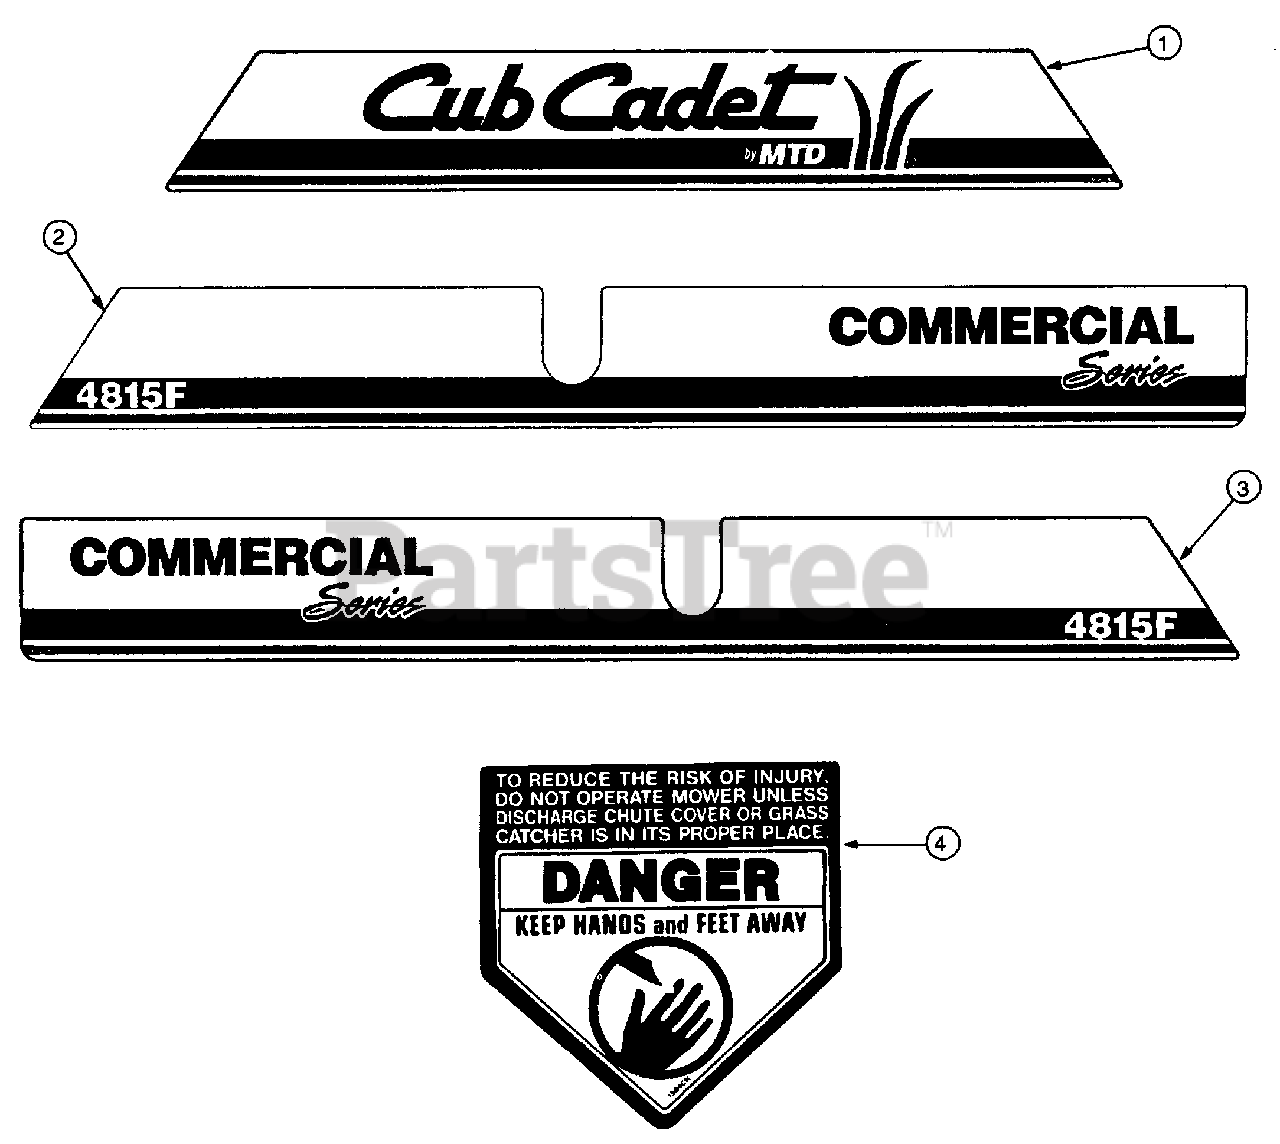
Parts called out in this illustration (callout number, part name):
1	Graphic, Belt Cover Front
2	Graphic 4815F, Belt Cover Left
3	Graphic 4815F, Belt Cover Right
4	Graphic, Danger Cut Finger
